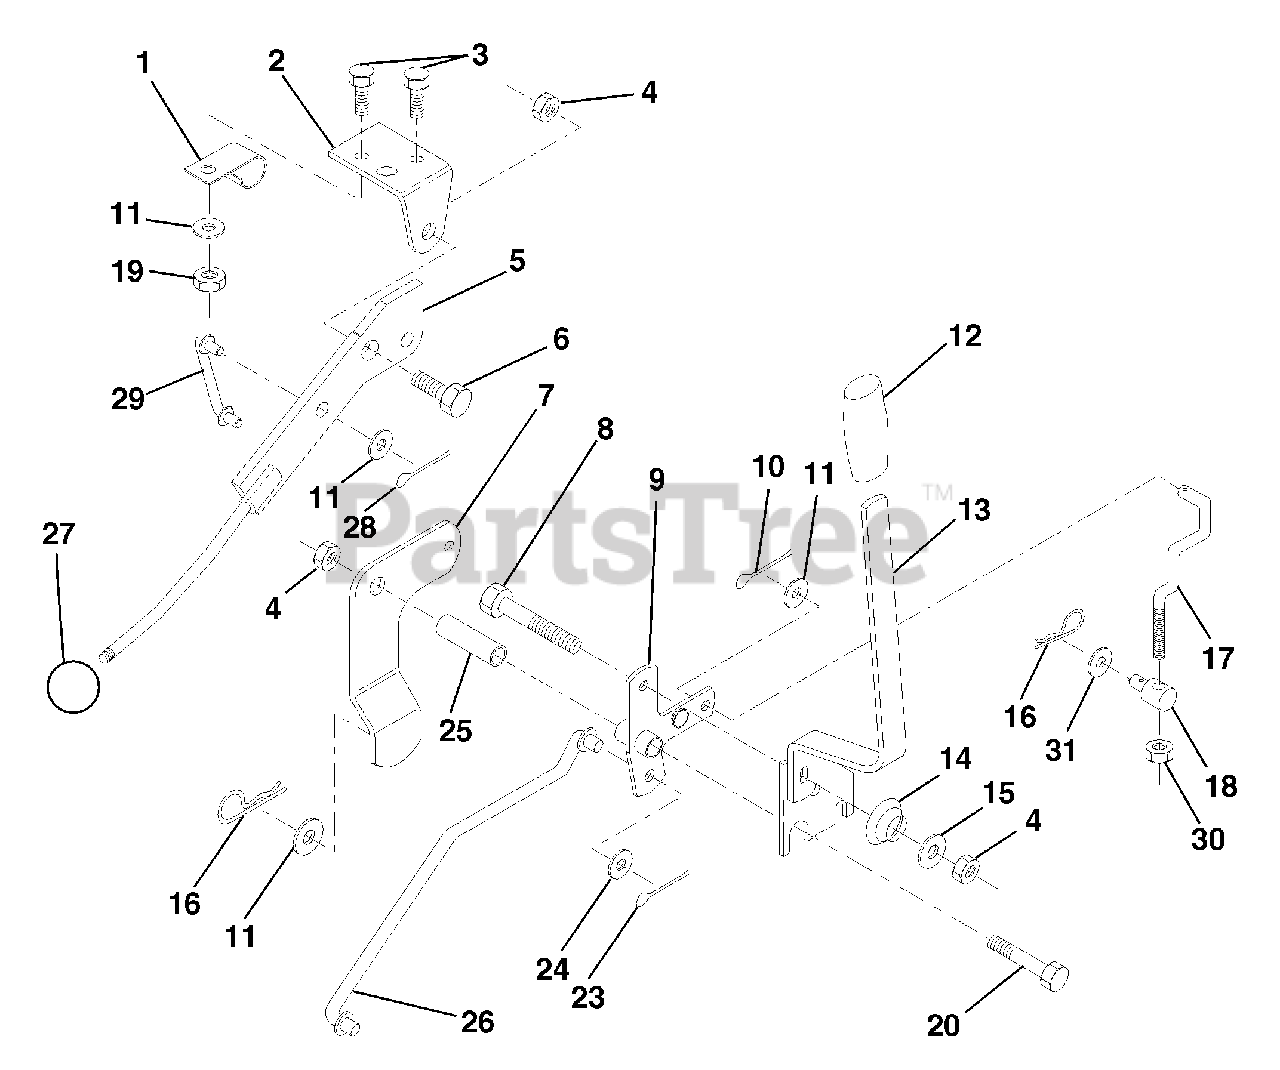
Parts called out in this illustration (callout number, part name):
1	Clip, Insulated
2	Bracket, Mower Clutch
3	Bolt, Fin. Hex 1/4-20 UNC x 1/2 Gr. 5
4	Nut, Crownlock 3/8-16 UNC
5	Assembly, Clutch Lever
6	Bolt, Shoulder
7	Assembly, Mower Clutch Arm
8	Bolt, Hex 3/8-16 UNC x 2-1/4
9	Assembly, Bellcrank Lift
10	Pin, Cotter 1/8 x 3/4
11	Washer 13/32 x 13/16 x 16 Ga.
12	Grip, Handle
13	Assembly, Lift Handle
14	Spring, Compression
15	Washer 13/32 x 3/4 x 12 Ga.
16	Retainer, Spring
17	Link, Front Lift
18	Trunnion, Threaded 3/8-16
19	Nut, Crownlock 1/4-20
20	Bolt, Fin. Hex 3/8-16 UNC x 2-3/4
23	Pin, Cotter 1/8 x 1
24	Washer 17/32 x 1 x 12 Ga.
25	Tube, Spacer
26	Rod, Mower Lift
28	Pin, Cotter 3/32 x 3/4
29	Link, Mower Clutch
30	Nut Hex Jam 3/8-16 x 1.30
31	Washer 13/32 x 1-1/4 x 12 Ga.
